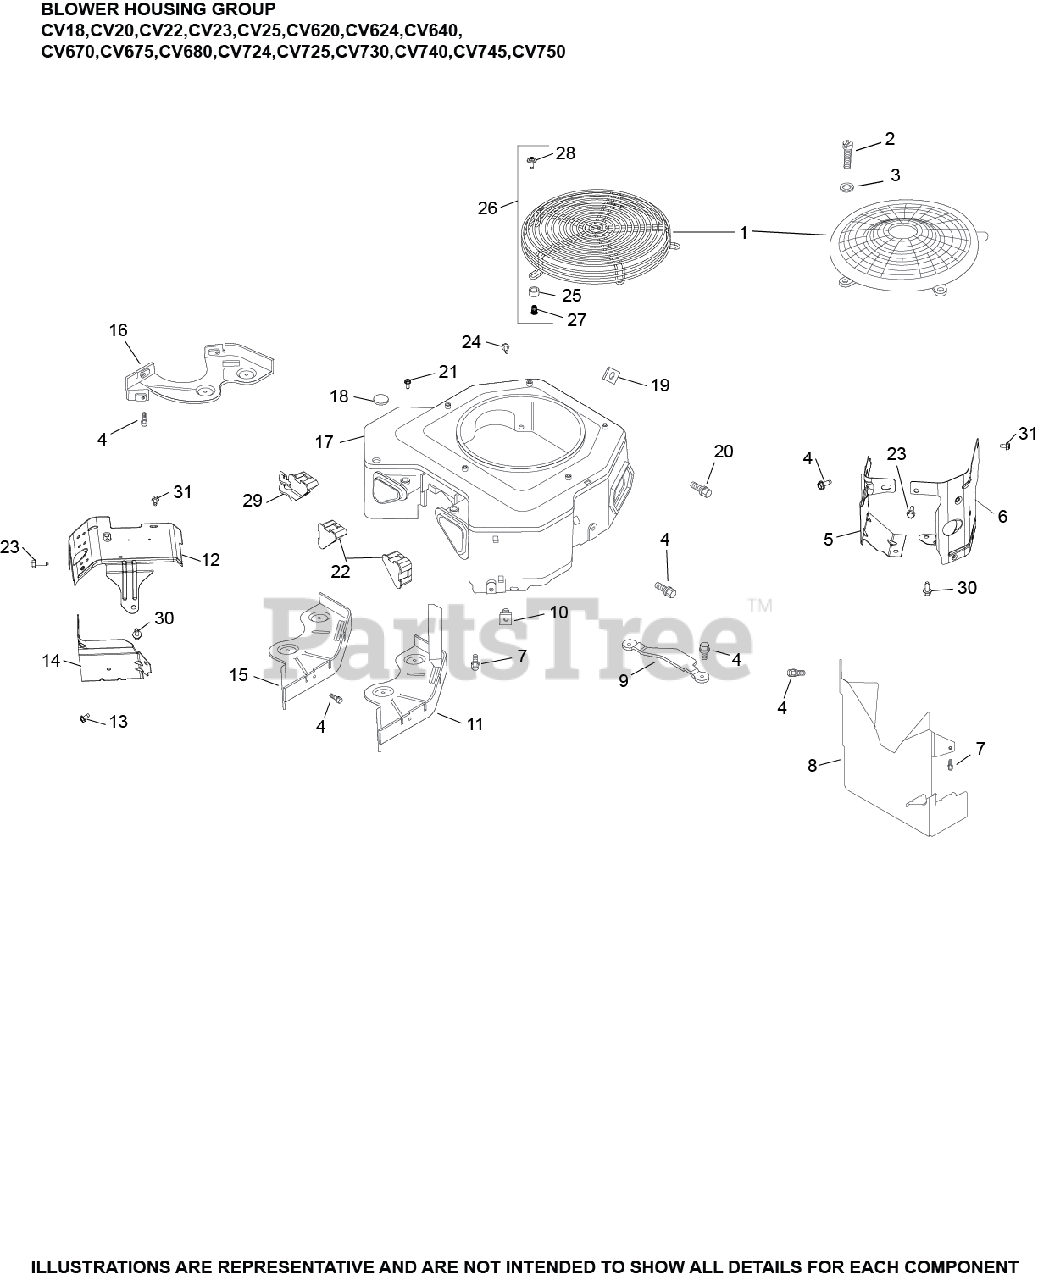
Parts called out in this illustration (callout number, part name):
5	BAFFLE, VALLEY #1 CYLINDER
6	KIT, CYL BAFFEL #2 SIDE
12	KIT, CYL BAFFEL #1 SIDE
14	BAFFLE, VALLEY #2 CYLINDER
15	KIT, BACKING PLATE
17	HOUSING, BLOWER
20	SCREW, THREAD FORMING
23	SCREW, THREAD FORMING
24	SCREW, THREAD FORMING
30	SCREW, THREAD FORMING
31	SCREW, THREAD FORMING
